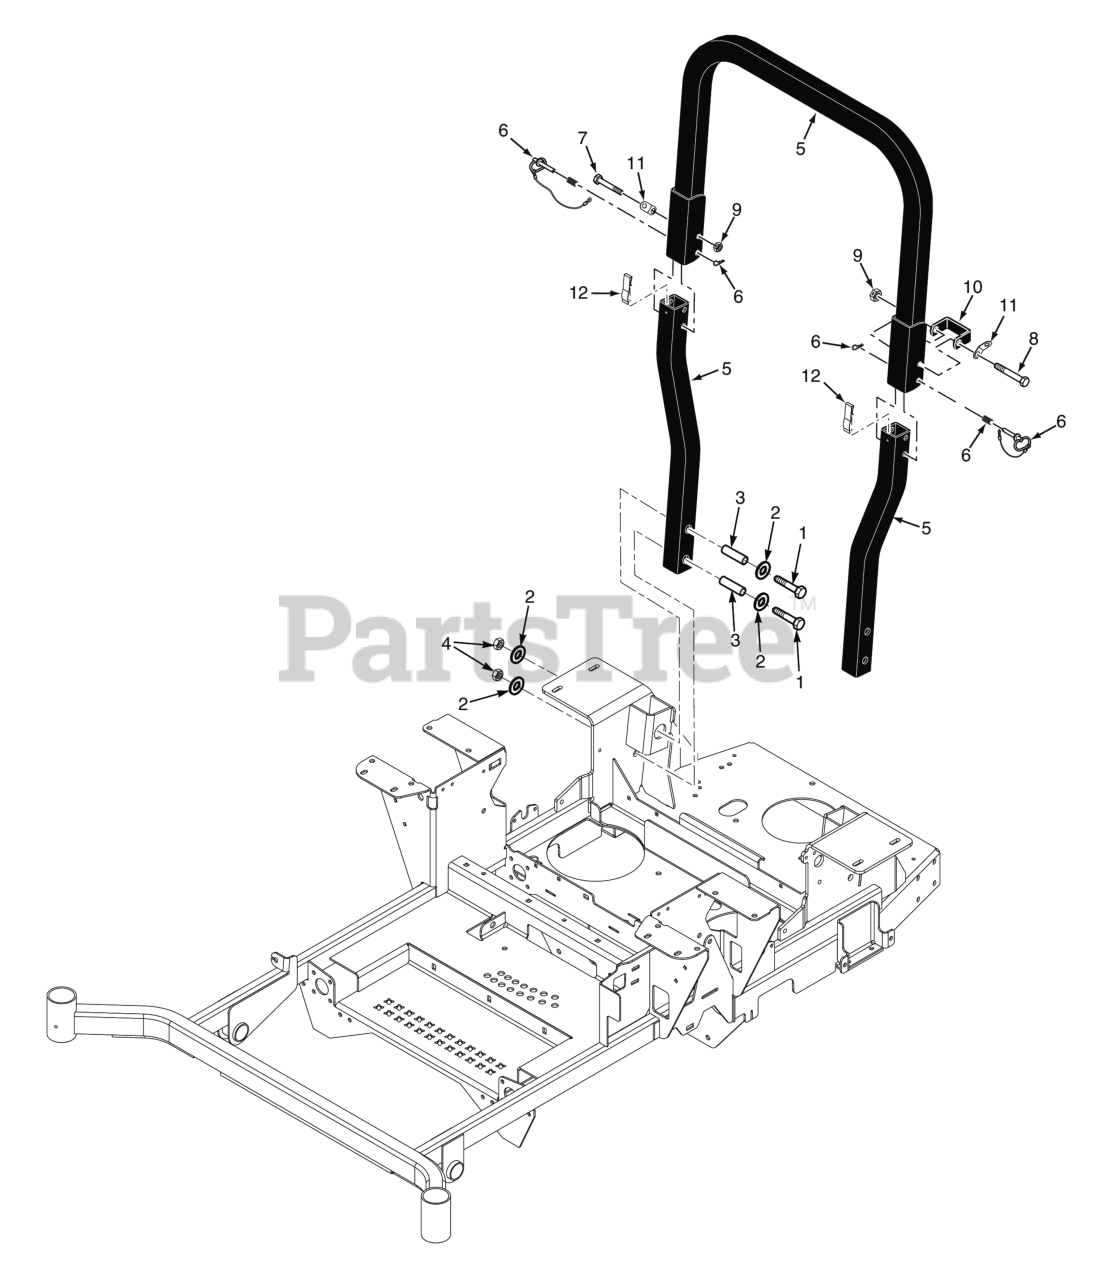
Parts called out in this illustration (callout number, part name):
1	Bolt, Hex Head 1/213 x 3" Gr. 8
2	Flatwasher, 1/2 - .531 x 1.062 x .095
3	Bushing, SFZ ROPS
4	Nut, Elastic Stop 1/2-13, (STT-52 & STTII-52)
5	ROPS, (Black)
5	ROPS, (Scag Gold)
6	Pin Assembly, ROPS Hinge
7	Bolt, Hex Head, 1/2-13 x 3-1/4"
8	Bolt, Hex Head 1/2-13 x 3-1/2"
9	Locknut, Hex 1/2-13 Center Lock
10	Stop, ROPS
11	Clip, ROPS
12	Spring, ROPS Anti-Rattle
